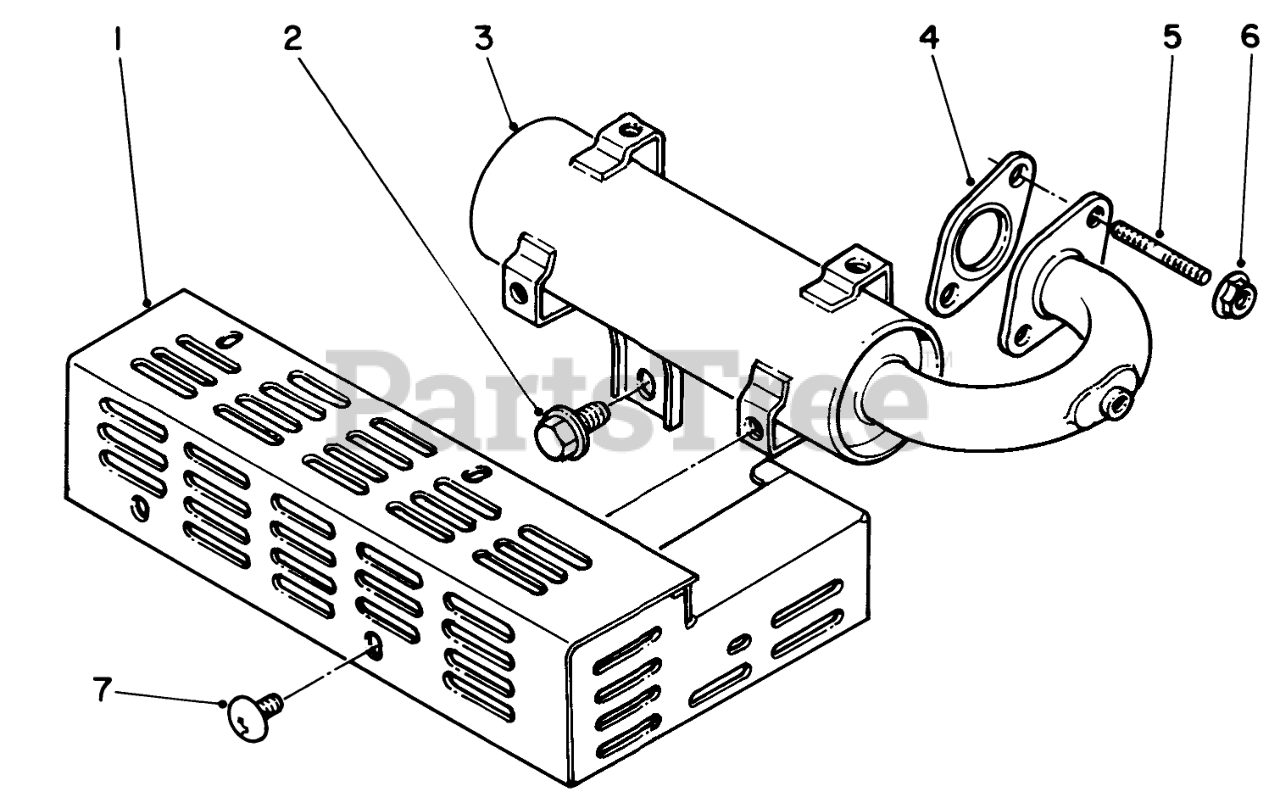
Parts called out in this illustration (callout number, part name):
1	Cover-Muffler
3	Muffler
4	Gasket
5	Bolt-Stud
7	Screw-Round Phillips Hd.
